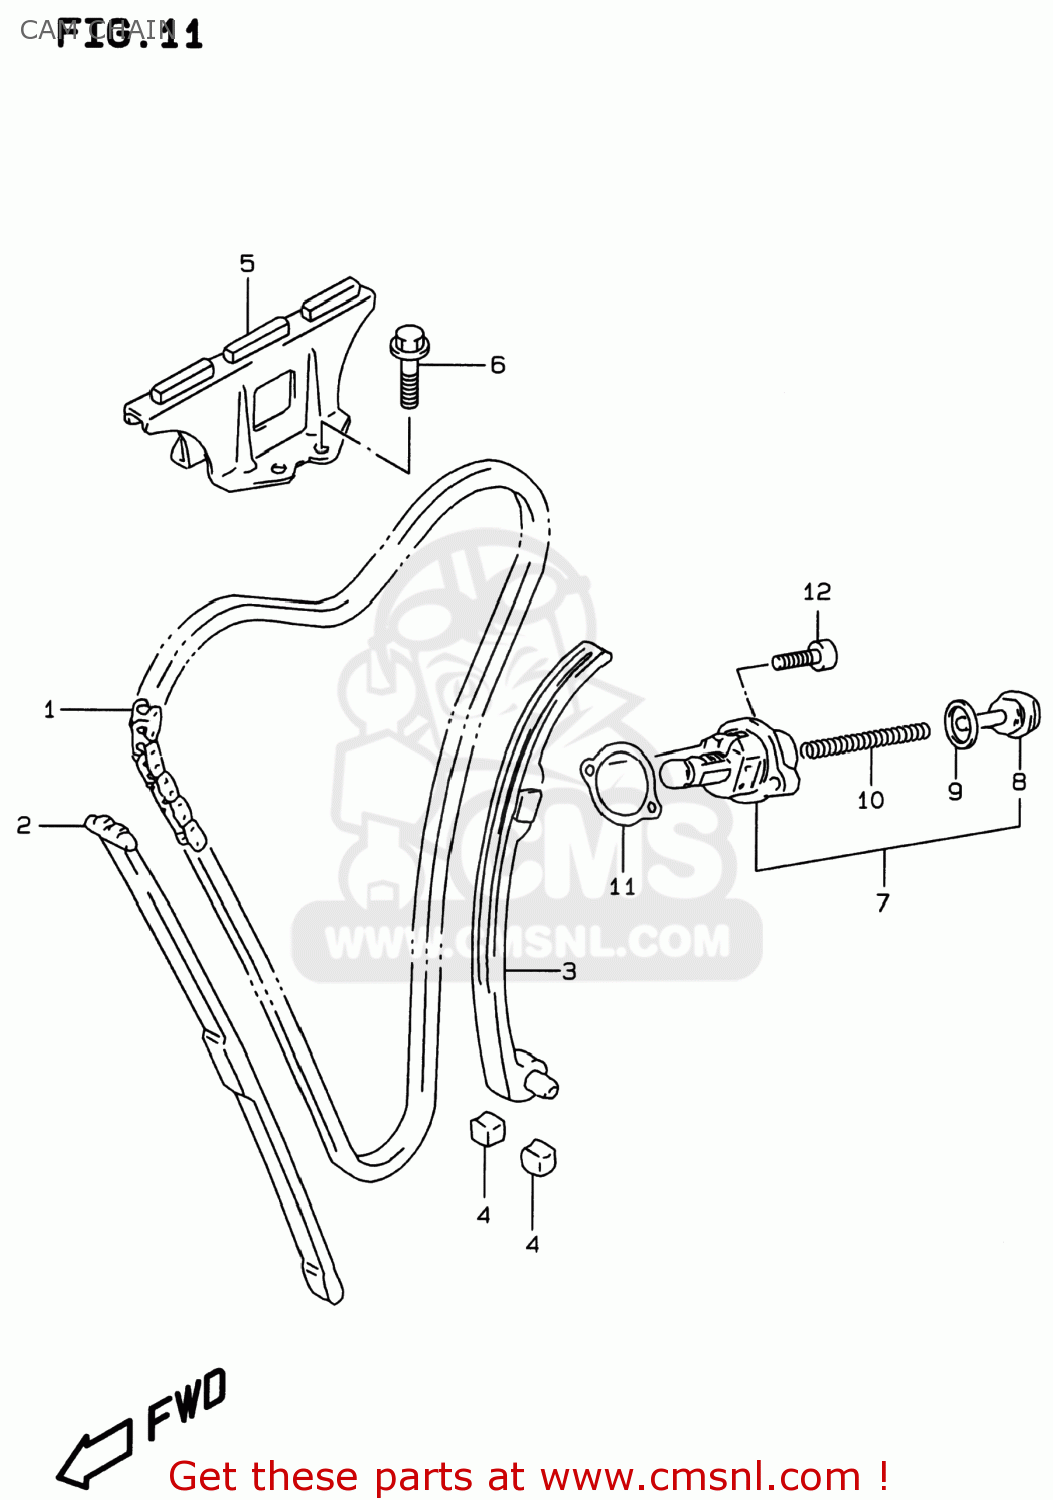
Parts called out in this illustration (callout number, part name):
1	CHAIN,CAMSHAFT DRIVE
2	GUIDE,CAM CHAIN NO.1
3	TENSIONER,CAM CHAIN
4	CUSHION,CAM CHAIN TENSIONER
5	GUIDE,CAM CHAIN NO.2
6	BOLT
7	ADJUSTER ASSY,TENSIONER
8	PLUG
9	GASKET (NAS)
10	SPRING
11	GASKET,TENSIONER ADJUSTER (NAS)
12	BOLT,CL.COVER
